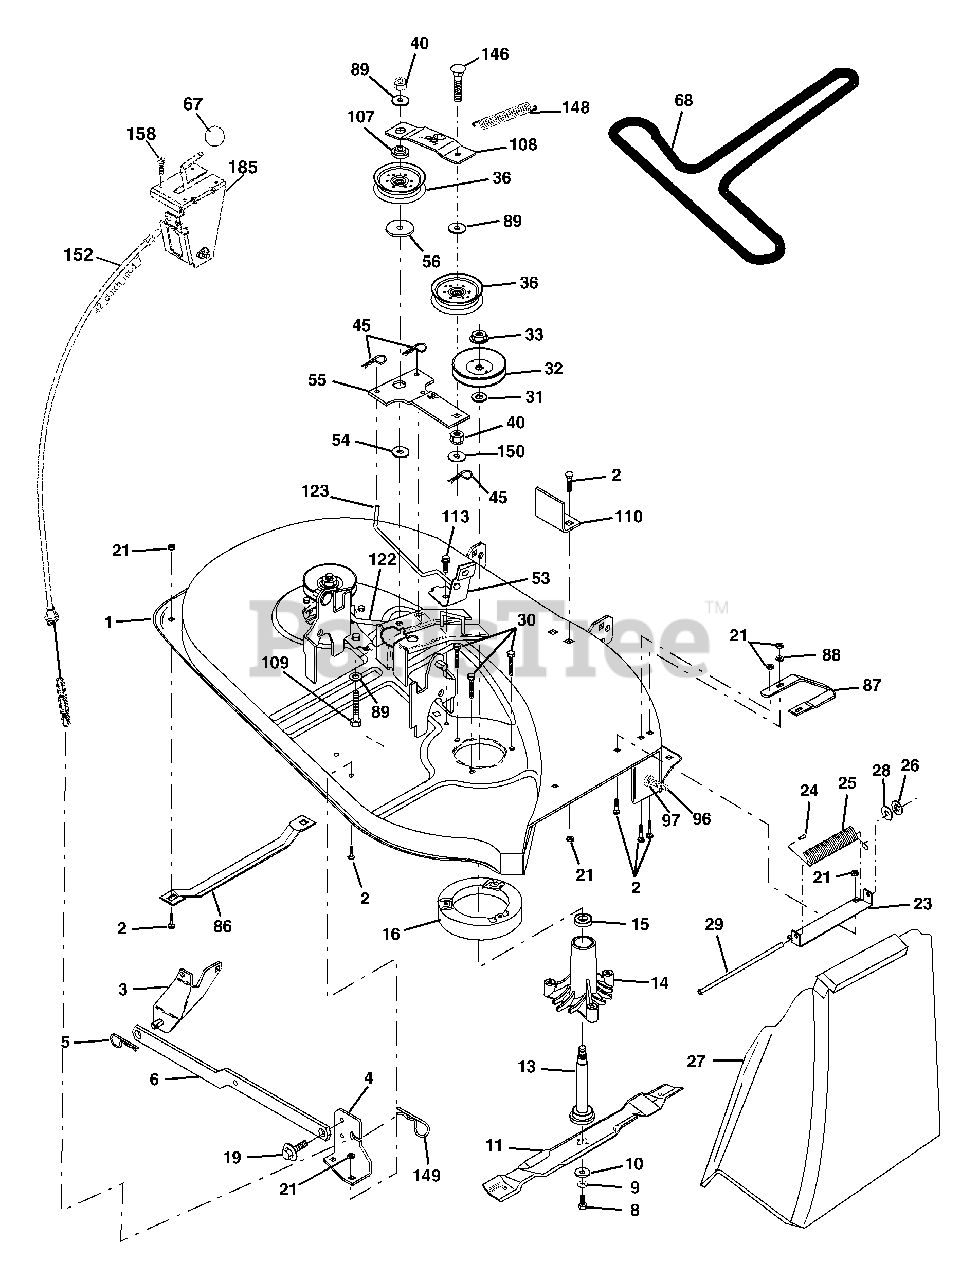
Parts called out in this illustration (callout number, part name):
1	Mower Housing Assembly
2	Bolt Carriage 5/16-18 x 3/4
3	Bracket Asm Fr. Sway Bar
4	Bracket Deck Sway Bar 38"/42"
5	Retainer Spring
6	Bar Sway Deck
8	Bolt 3/8-24 x 1.25 Gr. 8
9	Washer, Lock 3/8
10	Washer, Hardened
11	Blade, 38" Mulching Std
11	Blade, 38" Mulching Premium
11	Blade, 38" Hi-Lift
13	Shaft Assembly, Mandrel, Vented
14	Housing, Mandrel, Vented
15	Bearing, Ball, Mandrel
16	Stripper, Vented Mower Deck
19	Bolt, Shoulder
21	Nut
23	Bracket, Mower Deflector
24	Cap, Sleeve
25	Spring, Torsion, Deflector
26	Nut, Push
27	Shield, Deflector
28	Washer 11/32 x 5/8 x 16 Ga.
29	Rod, Hinge
30	Screw Thdrol. Washer Head
31	Washer, Spacer
32	Pulley, Mandrel
33	Nut, Toplock
36	Pulley, Idler, Flat
40	Nut, Crownlock 3/8-16 unc
45	Retainer
53	Brake Assembly
54	Washer, Hardened
55	Idler Arm Assembly
56	Spacer, Retainer
67	Knob
68	V-Belt, 42" Mower
86	Runner, LH
87	Runner, RH
88	Washer 11/32 x 3/4 x 16 Ga.
89	Washer 13/32 x 13/16 x 11 Ga.
96	Bolt 3/8-16 x 1-1/4 Mulcher
97	Nut Centerlock 3/8-16 unc
107	Spacer Retainer
108	Stiffener, Idler Arm
109	Bolt, Hex Hd 3/8-16 x 2-1/2
110	Upstop Deck Front 38"
113	Screw 5/16-1/ x 3/4
122	Rod, Brake LH
123	Rod, Brake RH
146	Bolt Carriage Idler
148	Spring Return Idler
149	Retainer Spring Yellow
150	Washer 9/32 x 3/4 x 10 Ga.
152	Clutch Cable 38"/46"
158	Screw Hex Thd Cut 1/4-20 x 1/2
185	Head Asm Cable Clutch
